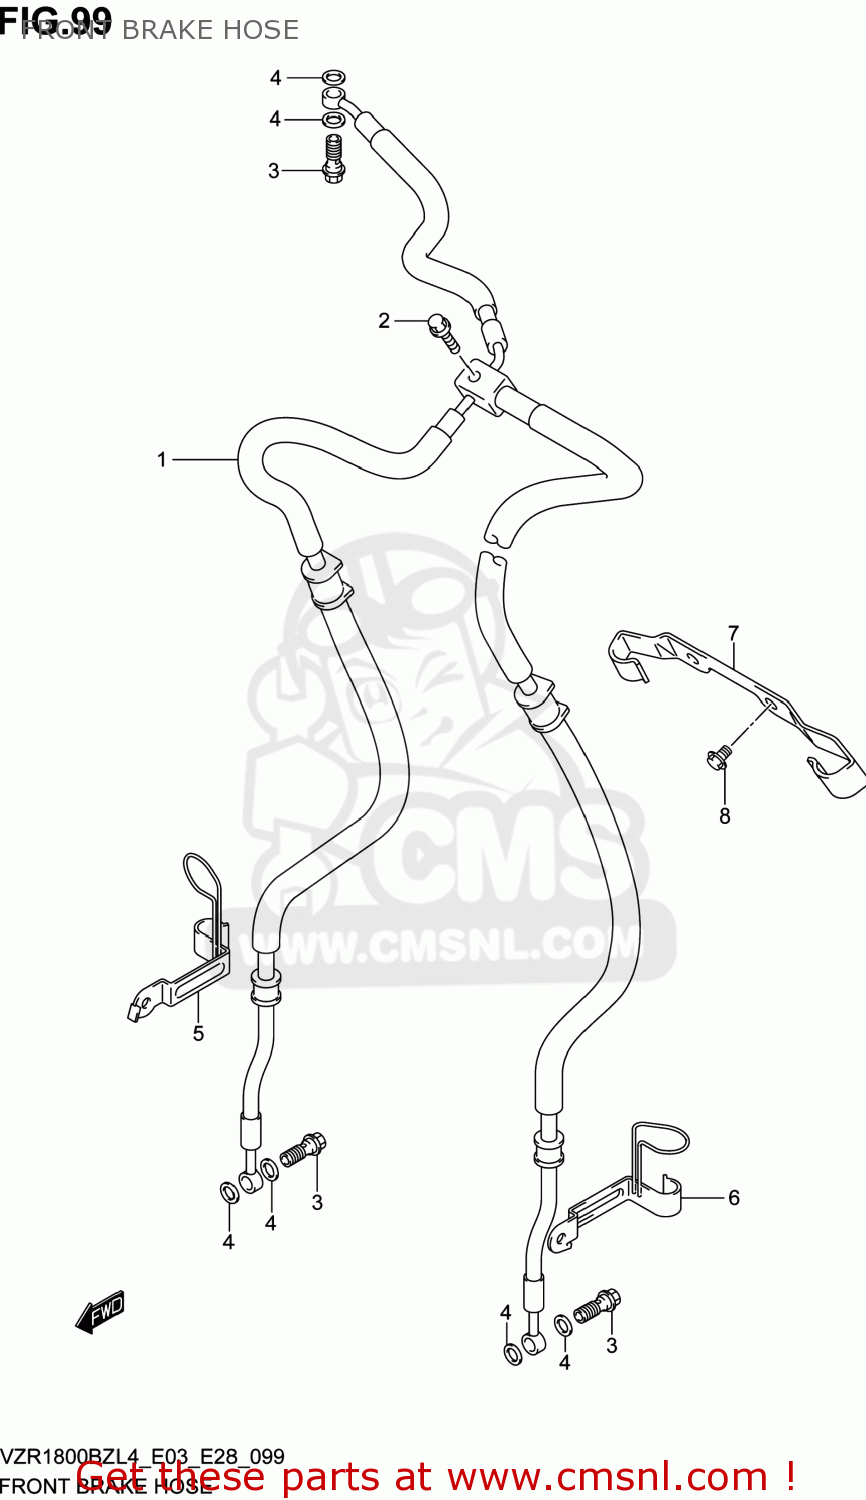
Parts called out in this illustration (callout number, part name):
1	HOSE,FR BRAKE
2	BOLT
3	BOLT UNION
4	WASHER(10X15X1.5)
5	CLAMP,FR BRAKE HOSE,R
6	CLAMP,FR BRAKE HOSE,L
7	CLAMP,FR BRAKE HOSE
8	BOLT
